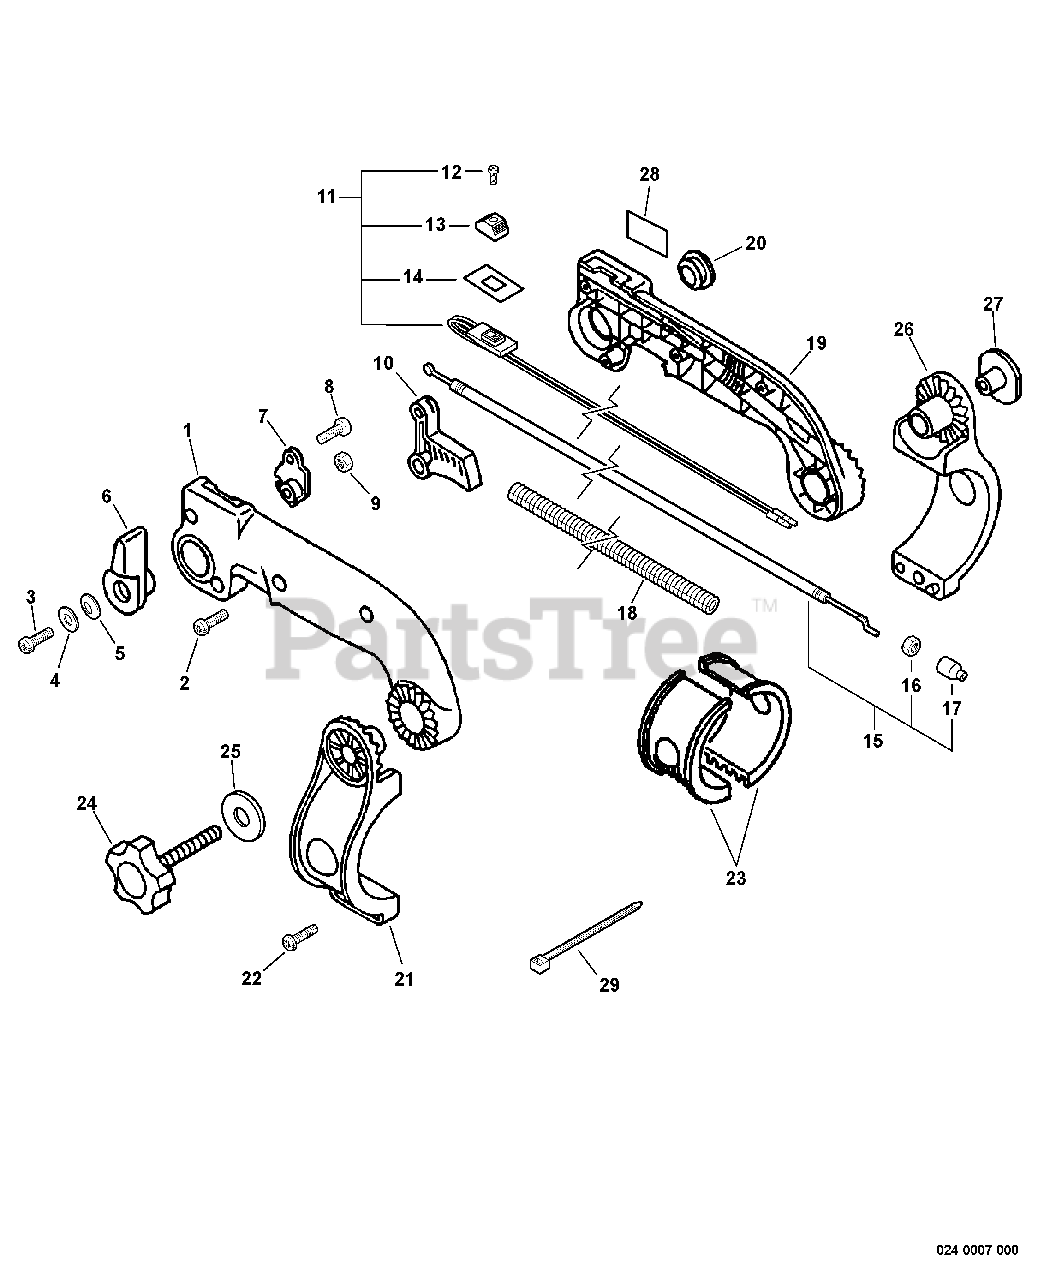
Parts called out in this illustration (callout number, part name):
1	HANDLE, CONTROL - LEFT
2	SCREW - 4X22
3	SCREW - 6X20
4	LOCKWASHER - 6
5	WASHER - 6
6	CONTROL, THROTTLE
7	BRACKET, THROTTLE
8	SCREW - 4X10
9	LOCKNUT - 6
10	TRIGGER, THROTTLE
11	IGNITION SWITCH ASSY
12	SCREW - 3X10
13	KNOB, SWITCH - ORANGE
14	COVER, SWITCH - STOP
15	CABLE, THROTTLE
16	LOCKNUT - 6
17	CAP, DUST
18	TUBE, PROTECTIVE - CORRUGATED
19	HANDLE, CONTROL - RIGHT
21	BRACKET, HANDLE - LEFT
22	SCREW - 5X20 -- TAPPING
24	THUMBSCREW
25	WASHER - 6
26	BRACKET, HANDLE - RIGHT
28	LABEL - STOP
29	TIE, CABLE - LARGE
